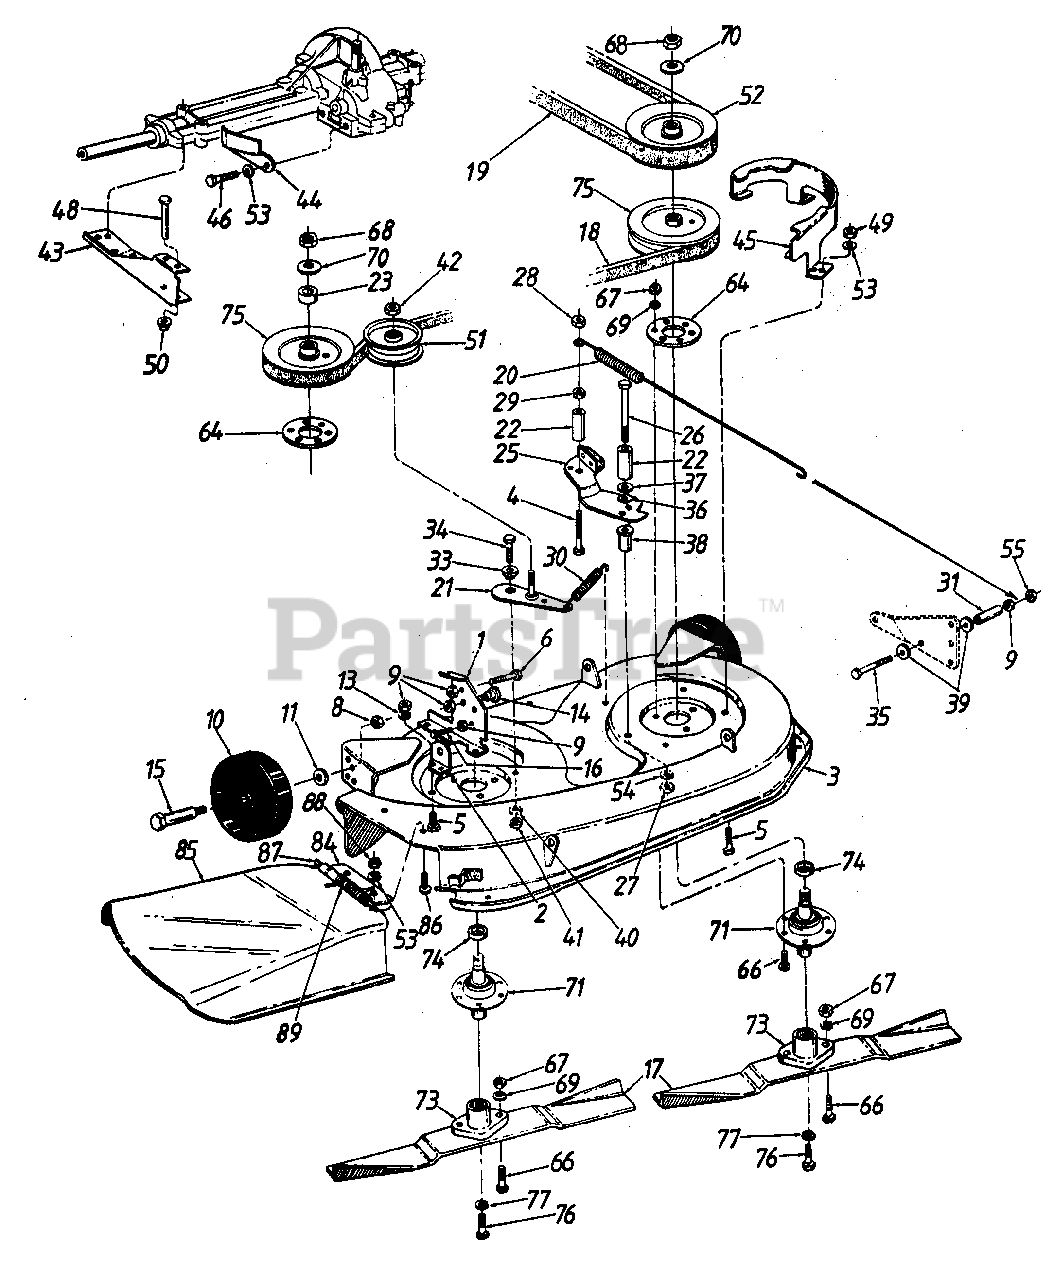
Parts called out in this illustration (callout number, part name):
1	Deck Disengagement Brkt.
2	Rear Deck Brkt.-R.H.
3	32" Deck Ass'y.
4	Hex Bolt 1/4-28 x 1.75" Lg.
5	Hex Bolt 1/4-20 x .62" Lg.*
6	Hex Wash. Hd. Scr. 1/4-20 x 1.5" Lg.
8	Hex L-Nut 3/8-16 Thd.
9	Hex Nut 1/4-20 Thd.
10	Deck Wheel
11	Bell-Wash. .380" I.D. x .88"
13	L-Wash. 1/4" I.D.
14	Shld. Bolt .500" Dia. x .215"
15	Shld. Bolt .498" Dia. x 1.53"
16	Hex Tap Scr. 1/4-20 x .75" Lg.
17	R.H. High-Lift Blade
18	V-Belt
19	V-Belt
20	Extension Spring 15-518" Lg.
21	Idler Brkt. Ass'y.
22	Spacer 5116" I.D. x 1/2" O.D. x 3/132"
23	Spacer .752" I.D. x 1.25" O.D.
25	Deck Brake Brkt. Ass'y.
26	Hex Bolt 5/16-18 x 3.25" Lg.
27	Hex Nut 5/16-24 Thd.
28	Hex L-Nut 1/4-28 Thd.
29	Hex Nut 1/4-28 Thd.
30	Extension Spring 4.35" Lg.
31	Spacer 1/4" I.D. x 3/8" O.D. x 1-5/16"
33	Shoulder Spacer
34	Hex Bolt 3/8-16 x 1" Lg.
35	Hex Bolt 1/4-20 x 2.5" Lg.
36	Wave Washer
37	Shld. Spacer .27" Lg.
38	Spacer 1.46" Lg.
39	Flat Wash. 1/4"
40	L-Wash. 3/8" I.D.
41	Hex Nut 3/8-16 Thd.
42	Hex L-Nut 3/8-24 Thd.
43	Lower Outside Belt Guard
44	Lower Inside Belt Guard
45	Belt Guard Deck-R.H.
46	Hex Bolt 1/4-20 x .62" Lg.
49	Hex Nut 1/4-20 Thd.
50	Speed Nut 1/4" Rod
51	Flat Idler Pulley
52	5" Dia. Pulley
53	L-Wash. 1/4" I.D.
54	Bell-Wash. 5/16" I.D.
55	Hex L-Nut 1/4-20 Thd.
64	Reinforcement Plate
66	Hex Bolt 5/16-24 x 1" Lg.
67	Hex Nut 5/16-24 Thd.
68	Hex Jam Nut 5/8-18 Thd.
69	L-Wash. 5/16" I.D.
70	Bell-Wash. 5/8" I.D.
71	Blade Spindle Ass'y. Comp.
73	Blade Adapter
75	5" Dia. Pulley
76	Hex Bolt 3/8-24 x 1.0" Lg.
77	L-Wash. 3/8" I.D. H.D.
84	Chute Bracket
85	Chute
86	Truss.-Mach. Scr. 1/4-20 x .75" Lg.
87	Hinge Pin
88	Hex Nut 1/4-20 Thd.
89	Torsion Spring 1.14" Lg.
